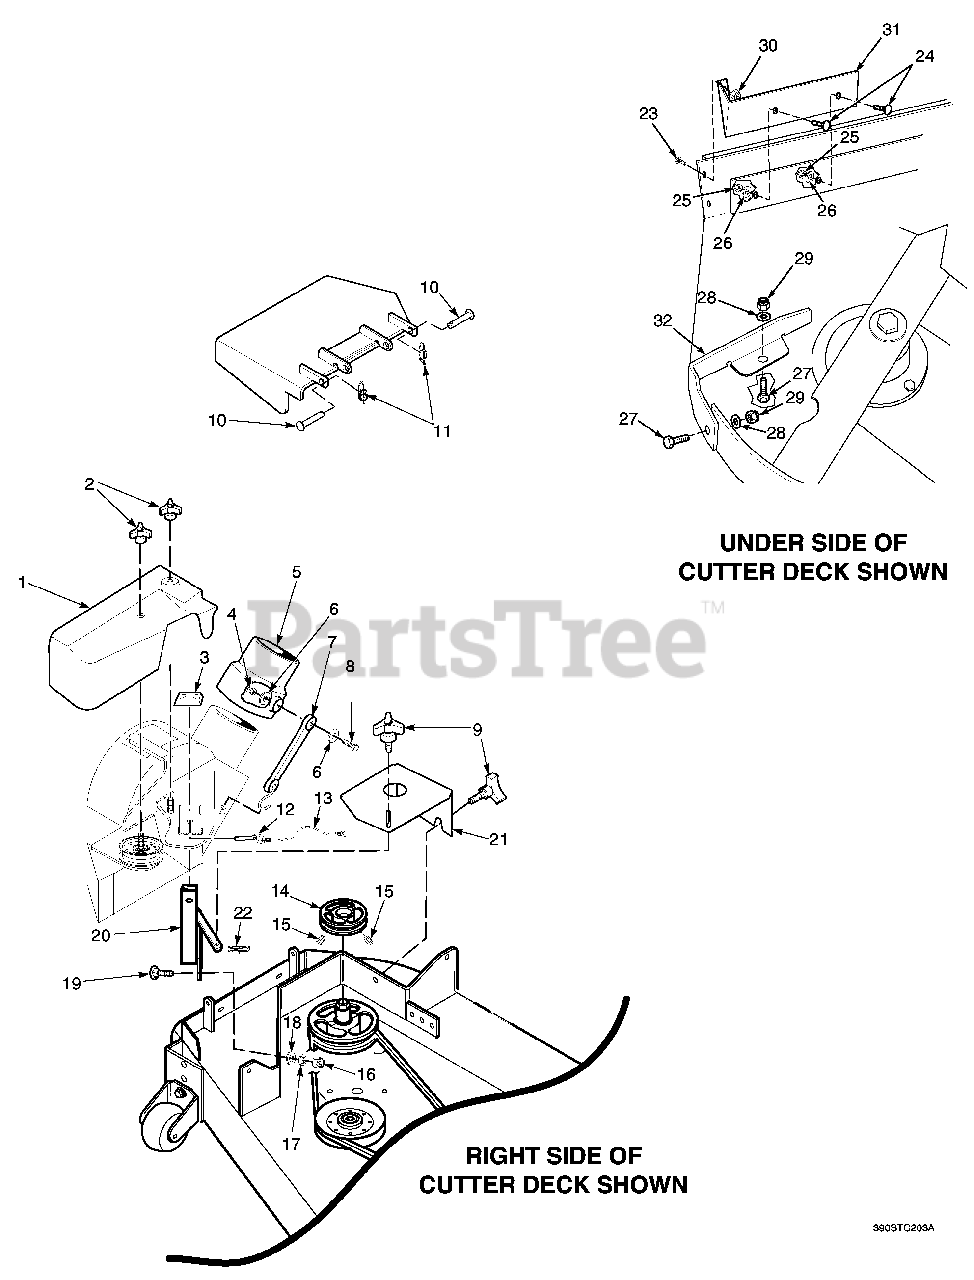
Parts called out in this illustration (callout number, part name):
1	Belt Cover, GC-STC
2	Wingnut, Plastic 3/8" Small
3	Cap, Square Vinyl
4	Nut, Elastic Stop 1/4-20
5	Adapter, Blower GC-STC,
6	Flatwasher, 1/4-.312 x .750 x .065
7	Rubber Strap 7-3/4"
8	Bolt, Hex Head 1/4-20 x 1-1/4"
9	Knob W/Stud, 3/8-16 x 1-1/4"
10	Clevis Pin, 5/16 x 1-1/2"
11	Pin, Rue Cotter 5/16 Dia.
12	Pin, Ring 1/2 x 2-1/4"
13	Lanyard
14	Pulley, 3-3/4" for 48" Deck
15	Setscrew, 5/16-18 x 3/8"
16	Nut, Elastic Stop 3/8-16
17	Lockwasher, 3/8"
18	Flatwasher, 3/8-.391 x .938 x .105
19	Bolt, Carr. 3/8-16 x 1-1/4" Grade 5
20	Mounting Post Weldment, Blower
21	Belt Cover
23	Bolt, Hex Head 1/4-20 x 3/4"
24	Bolt, Carriage 3/8-16 x 1"
25	Nut, Elastic Stop 3/8-16
26	Flatwasher, 3/8-.391 x .938 x .105
27	Bolt, Hex Head 5/16-18 x 1"
28	Flatwasher, 5/16-.375 x .875 x .083
29	Nut, Elastic Stop 5/16-18
30	Nut, Serrated Flange 1/4-20
31	Baffle, 48"
32	Baffle, 48" Deck
